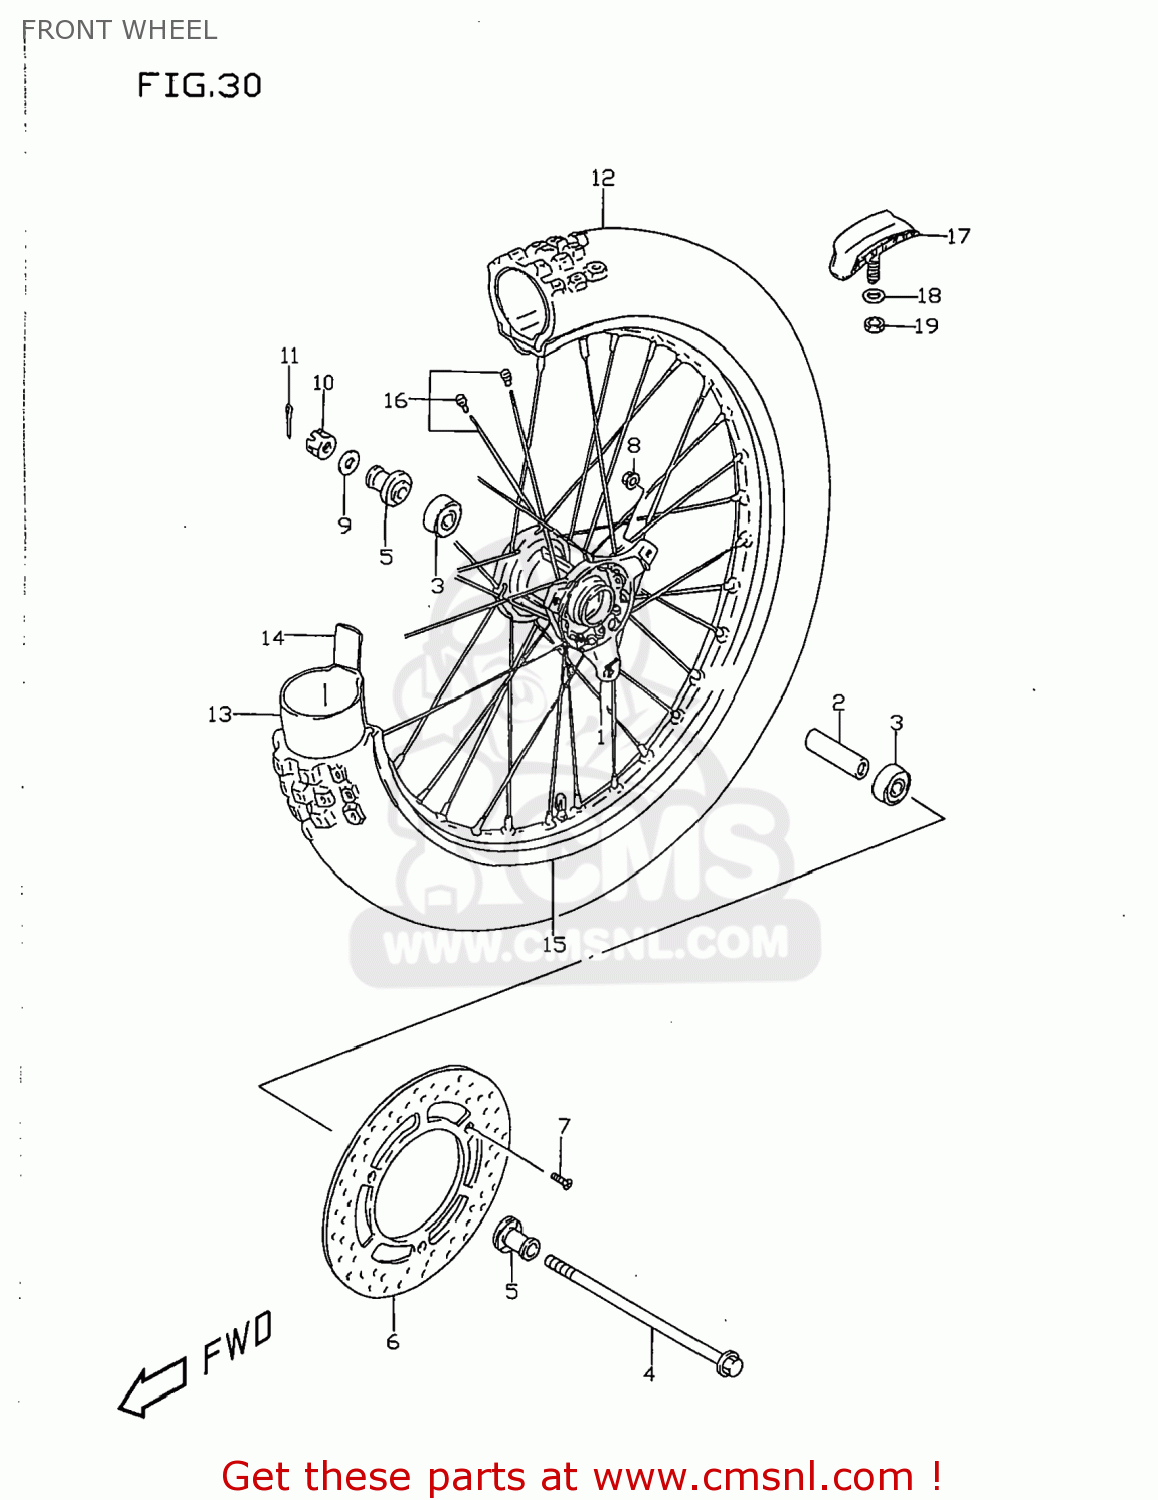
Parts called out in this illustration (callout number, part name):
1	PISTON SET
2	SEAL SET,PISTON
3	PAD SET (NAS)
4	SHIM,PAD
5	SPRING,PAD
6	BOOT,AXLE
7	INSULATOR,AXLE
8	PIN,PAD
9	CLIP,PAD PIN
10	BLEEDER
11	CAP,BLEEDER PLUG
12	GUIDE,PAD
13	CARRIER,CALIPER,L
14	BOLT(8X41)
